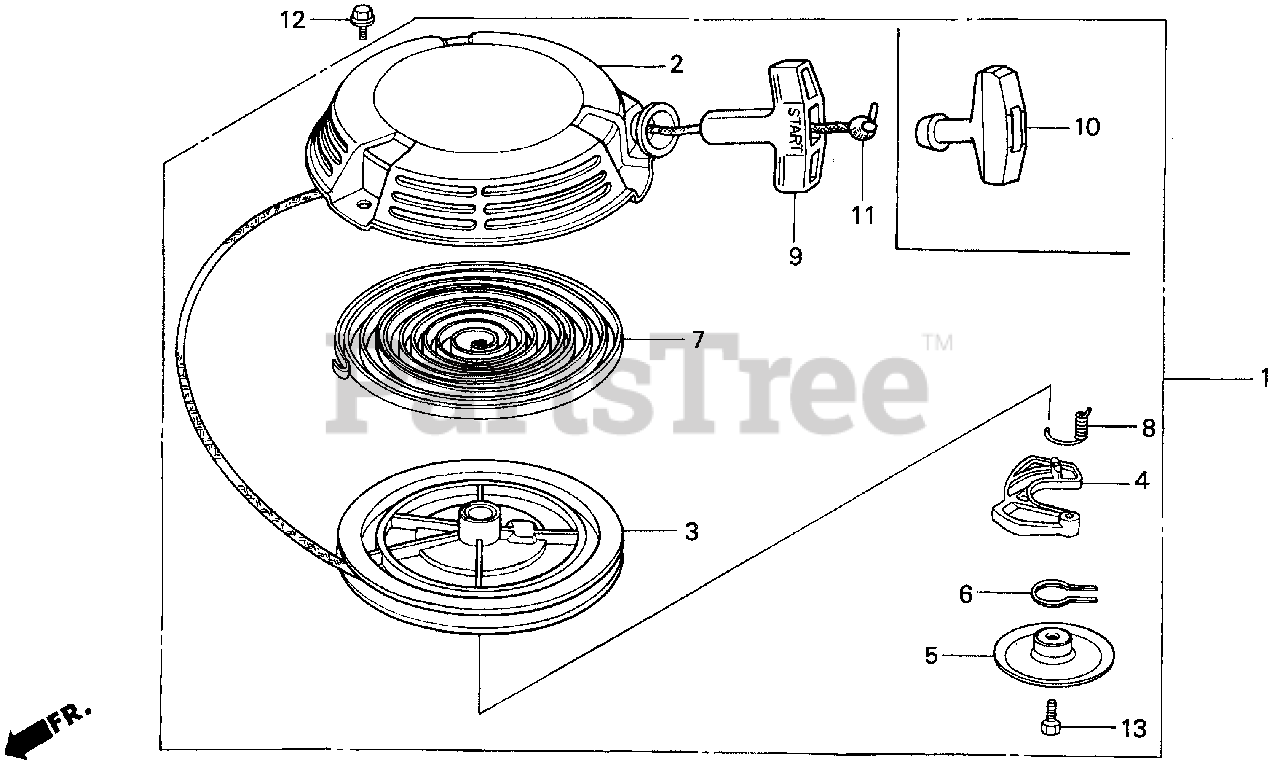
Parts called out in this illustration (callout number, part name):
1	STARTER ASSY., RECOIL *R8* (BRIGHT RED)
2	CASE, RECOIL STARTER *R8* (Honda Code 3352754). (BRIGHT RED)
3	PULLEY, RECOIL STARTER
4	RATCHET, STARTER
5	PLATE, FRICTION
6	SPRING, FRICTION
7	SPRING, RECOIL STARTER
8	SPRING, RETURN
9	KNOB, RECOIL STARTER
11	ROPE (#4X91")
12	BOLT, FLANGE (6X8)
13	BOLT, HEX. (6X20)
